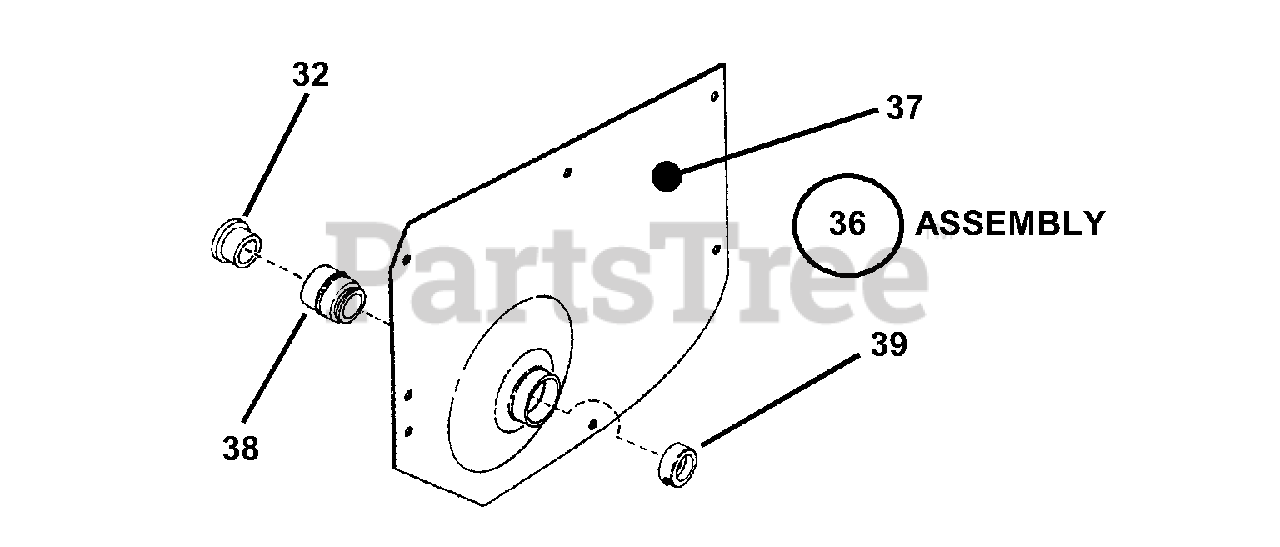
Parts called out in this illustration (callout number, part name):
32	SPACER
36	ASS'Y, L. H. Fender & Ball Bearing
37	FENDER, Left Hand (1.744" I.D. hole)
38	BALL BEARING, Left Hand Fender
39	COLLAR, Lock
